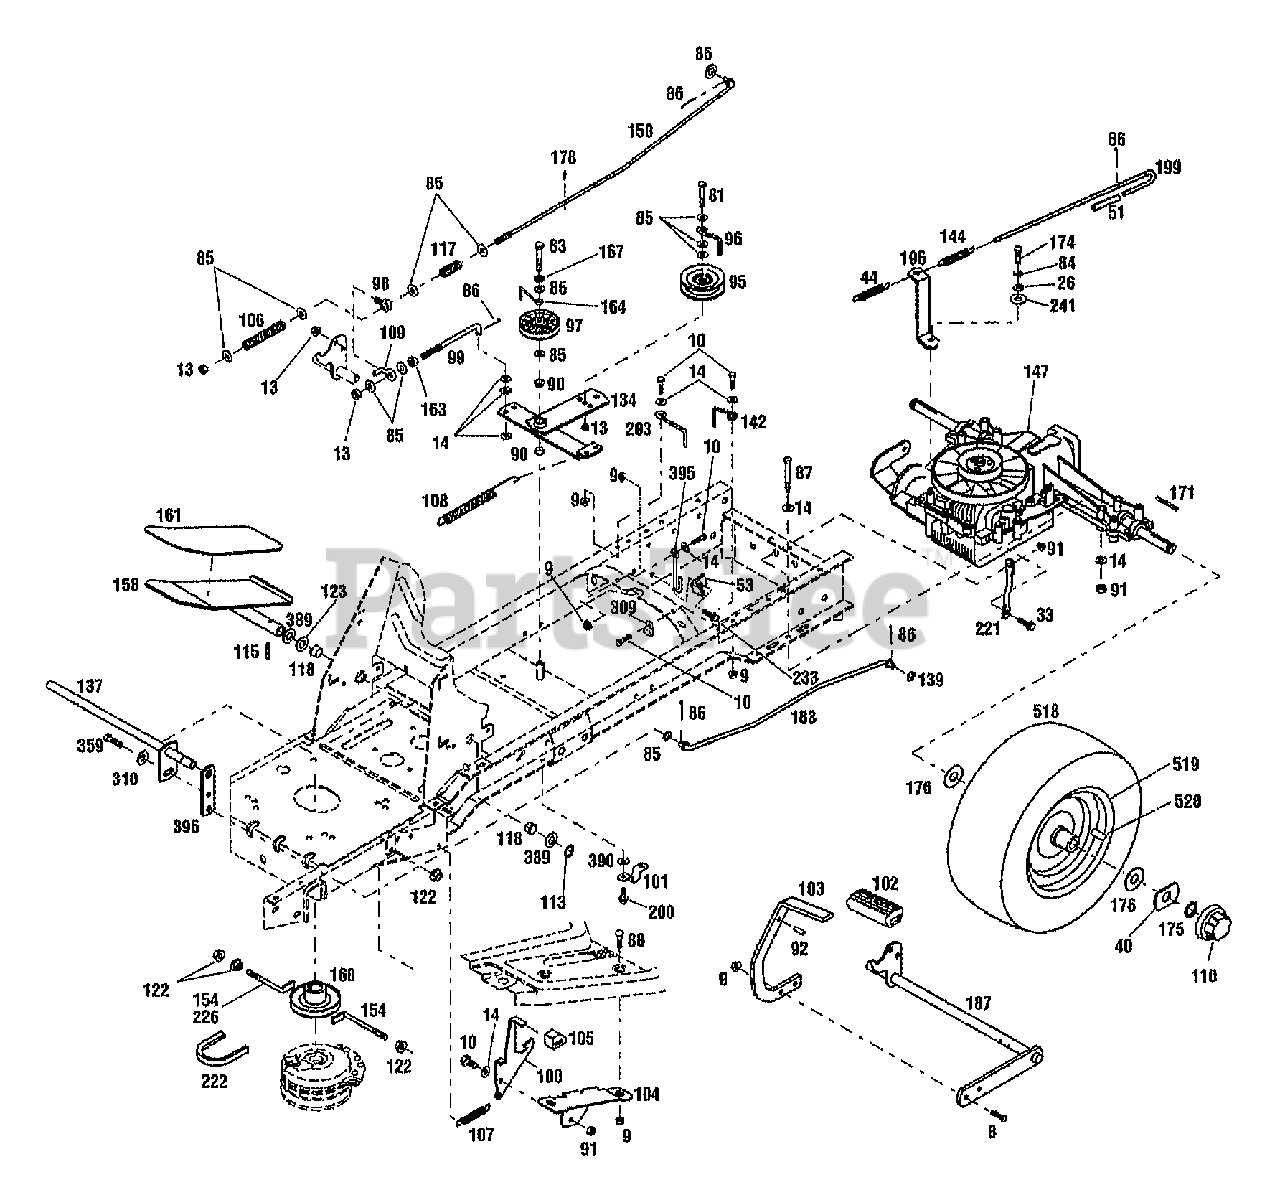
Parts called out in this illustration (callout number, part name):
8	SCR-HH 5/16-18X1.0 G5 ZP
9	NUT-HFLK 5/16-18 ZP
10	SCR-HHC 5/16-18X.75 GR 5 ZP
13	NUT-LOCK 3/8-16
14	WASHER-FLAT 5/16 SAE
26	WASHER-.75X.312X.065 ZP
33	SCR-HFLK 5/16-18X.75
40	WASHER-SPEC .75X2.50
44	SPRING-EXTENSION
51	GRIP-HANDLE
53	BRACKET-STOP
81	SCR-HH 3/8-16X2.0 G5 ZP
83	SCR-HH 3/8-16X1.75 G5 ZP
84	WASHER-LK .25 ZP
85	WASHER-FLAT 3/8 SAE
86	PIN-COTTER .09X.75 ZP
87	SCR-HH 5/16-18X2.75 G5 ZP
88	SCR-CARR 5/16-18X.62 G2 ZP
90	BUSHING-.5X.5 NYLON FLNG
91	NUT-TOP/LK 5/16-18 ZP
92	PIN-DRIVE .312X.75
96	GUIDE-BELT
97	PULLEY-IDLER
98	BOLT-EYE
99	ROD-CLUTCH
100	LATCH-BRAKE LOCK
101	CLIP-CLAMP .75 ID
102	PAD-FOOT PEDAL
103	PEDAL-BRAKE
104	BRKT-BRAKE LOCK
105	PAD-BRAKE
106	SPRING-COMPRESSION
107	SPRING-EXTENSION
108	SPRING-EXTENSION
109	ROD-PIVOT
110	CAP-HUB
113	RING-RETAIN .625 ID
115	PIN-ROLL .188X1.0
117	SPRING
118	BEARING-FLANGE
122	NUT-HFLK 3/8-16 ZP
123	WASHER-1.115X.637X.06
134	ARM-IDLER
137	SHAFT-HYDRO PIVOT
139	WASHER-FLAT .375DIA
142	GUIDE-BELT
144	SPRING
147	TRANSAXLE-HYDRO
150	ROD-BRAKE
154	RETAINER-CLUTCH
158	ASSM-PEDAL HYDRO
160	PULLEY-ENGINE
161	PAD-FOOT PEDAL
163	NUT-HEX 3/8-16 ZP
164	GUIDE-BELT
167	WASHER-LK .375 @ DEPL
171	KEY-3/16X3/16X1 3/4
174	SCR-HHC 1.4-28 X .50
175	RING-RET."E".577 ID
176	WASHER-1.87X.765X.06 SPECIAL
178	PIN-DRIVE .09X.75
183	ROD-HYDRO CONTROL
187	ASSM-BRAKE PEDAL
196	ARM-DUMP VALVE
199	ROD-DUMP VALVE
200	SCR-HFLK 5/16-18X.75
203	GUIDE-BELT
221	SUPT-TRANSMISSION
226	GUIDE-BELT
233	SCR-HFLK 5/16-18X.62 G5ZP
309	CLIP-J
310	WASHER-LK .375 PYRAMIDAL
359	SCR-HH 3/8-16X.88 G5 ZP
389	WASHER-SHIM
390	WASHER-.632X.39X.0329
395	GUIDE-BRAKE ROD
396	ARM-CONTROL
518	TIRE-20X8.00-10
519	WHEEL-REAR
520	STEM-VALVE
